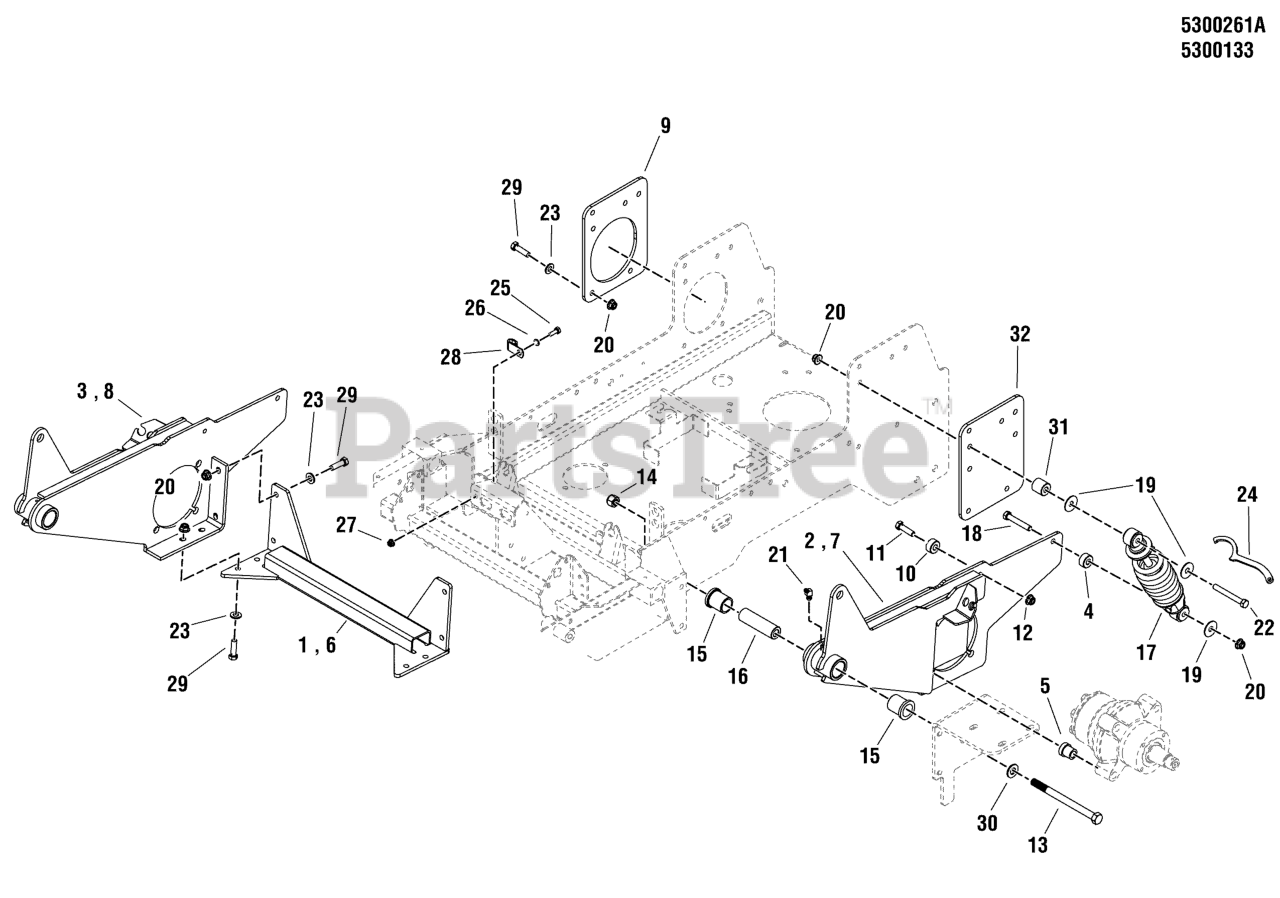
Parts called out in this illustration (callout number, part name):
1	KIT, TIE BAR
2	WELD, MOTOR MOUNT - LH - RED
3	WELD, MOTOR MOUNT - RH - RED
4	SPACER, .39 X 1.00 X .50
5	SPACER, .53 X 1.00 X 1.00, W/ FLAT, CZ
6	KIT, TIE BAR
7	WELD, MOTOR MOUNT - LH - RED
8	WELD, MOTOR MOUNT - RH - RED
9	PLATE, FRAME SUPPORT, RH - RED
10	SPACER, .34 X 1.54 X .25 UHMW
11	SCREW, 5/16-18 X 1 PHILLIPS HD, BZ
12	NUT, 5/16-18 HEX NYLOCK FLANGE
13	BOLT, 1/2-13 X 6-1/2 GD8 YZ
14	NUT, 1/2-13 HEX NYLON LOCK
15	BUSHING, FLANGE
16	SPACER, .52 X 1.00 X 3.42
17	SHOCK ABSORBER
18	BOLT, 3/8-16 X 2-1/4" GD5 CZ
19	WASHER-3/8 FENDER
20	NUT, 3/8-16 HEX NYLOCK FLANGE
21	GREASE FITTING, 45 DEGREE
22	BOLT, 3/8-16 X 3-1/2" GD5 CZ
23	WASHER, 3/8 GD.9 FLAT
24	WRENCH, SPANNER, CZ
25	BOLT, 1/4-20 X 3/4 GD5 YZ
26	WASHER, 1/4 SAE
27	NUT, 1/4-20 HEX NYLOCK FLANGE
28	CLAMP, 5/16, DOUBLE, WIRE & TUBE
29	BOLT, 3/8-16 X 1-1/4" GD5 CZ
30	WASHER, 1/2 SAE
31	SPACER, .390 X 1.00 X 1.00 - YZ
32	PLATE, FRAME SUPPORT, LH - RED
